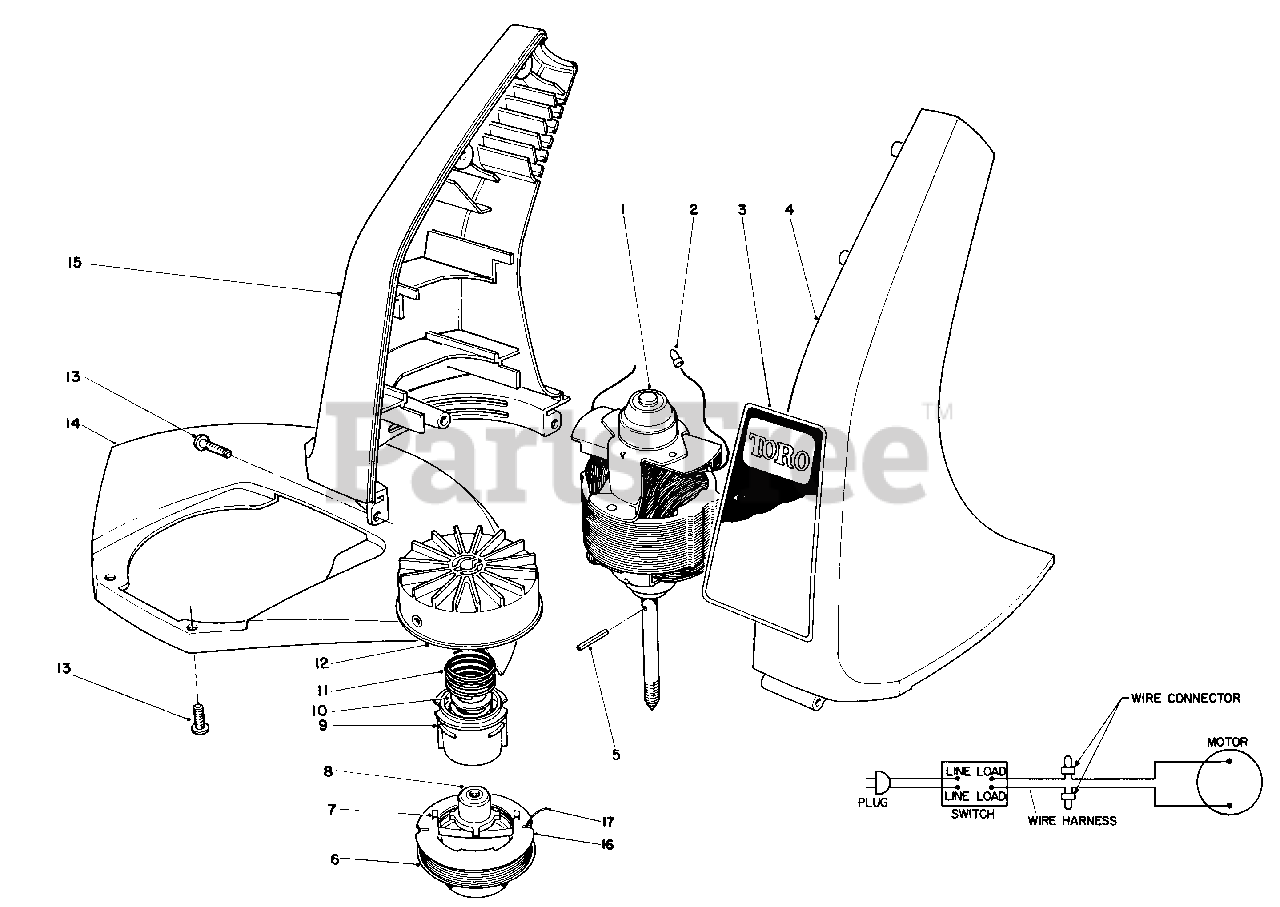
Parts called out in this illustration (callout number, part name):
2	Connector-Wire
3	Decal-12"
4	Housing-L.H.
6	Cutting Line (50 .065" Dia.)
7	Clip-Saddle
11	Spring-Compression
12	Drum w/Eyelet
13	Screw
14	Shield (Incl. Ref. #18 & 19)
15	Housing-R.H.
16	Spool-Empty
17	Cutting Line (50 .065" Dia.)
